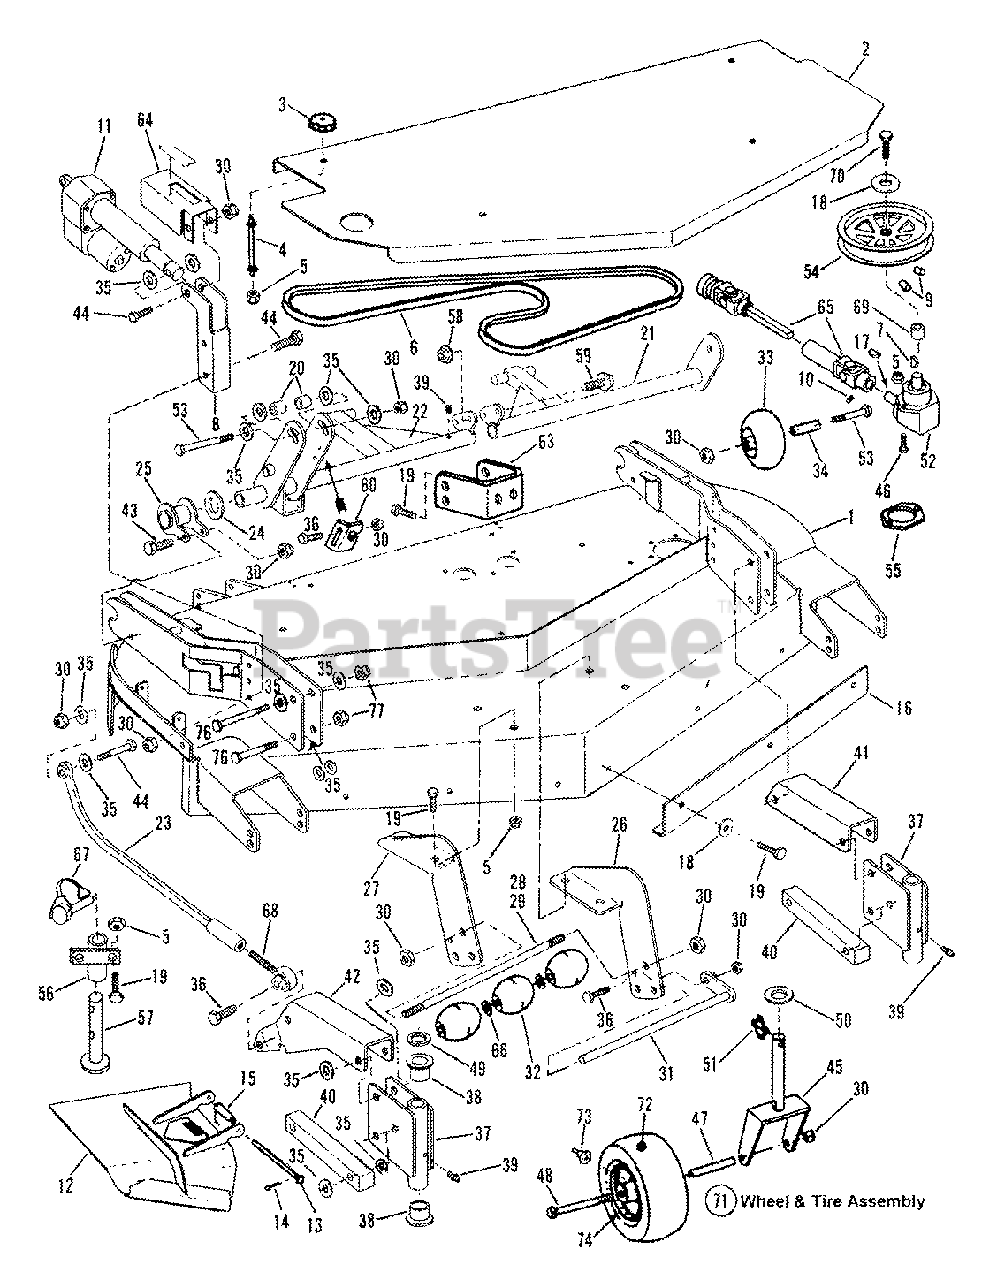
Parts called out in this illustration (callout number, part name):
1	WELDMENT, 61" Deck-Adjustable Height
2	COVER, 61" Deck
4	STANDOFF, 3-1/2"
5	NUT, 3/8-16 HEX NYLON LOCK
6	V-Belt, 61"(134.5") HB
7	KEY, 5/32 x 5/8 Woodruff
8	MOUNT, Motor (Front)
9	SCREW, 5/16-18 x 5/8" Set Yellow Zinc
10	SET SCREW, 3/8-16 x 3/8"
11	SCREWJACK, Warner Electric 1000 lbs.
12	DEFLECTOR, Chute 61" (Weldment)
13	PIN, Chute Hinge
14	PIN, 3/32 x 1" Cotter
15	SPRING, Chute
16	BAFFLE, Front
17	KEY. #9 Woodruff
18	WASHER, 13/32 x 1-1/2" Flat
19	BOLT, 3/8-16 X 1" GD5 CZ
20	SPACER, Motor, Rear
21	LINK, Weldment L.H.
22	LINK, Weldment R.H.
23	LINK, Height of Cut
24	SPACER, Tube
25	HOLDER, Pivot
26	MOUNT, Roller L.H.
27	MOUNT, Roller R.H.
28	TUBE, Roller
29	PIN, Roller
30	NUT, 1/2-13 Hex Nyloc
31	ASSEMBLY, Shaft
32	ROLLER, Low Density Polyethylene
33	WHEEL, Gage
34	SPACER, Gage Wheel
35	WASHER, 1/2" Flat
36	BOLT, 1/2-13 X 1-1/2 GD5 CZ
37	TUBE, Caster (Weldment)
38	BUSHING, Caster
39	FITTING, Lube 1/4-28 Straight
40	ARM, Lower Caster
41	ARM, Caster Support L.H.
42	ARM, Caster Support R.H.
43	BOLT, 1/2-13 x 3-3/4", Hex Head, Grade 5
44	BOLT, 1/2-13 X 3" GD5 CZ
45	WELDMENT, Caster
46	BOLT, 3/8-16 X 1-1/4" GD5 CZ
47	SLEEVE, Axle
48	BOLT, 1/2-13 X 5-1/2" GD5 YZ
49	SPACER, 1" x 1 3/8 x .30" (PM)
50	BUSHING, Machine
51	PIN, 7/16" HD Lynch
52	GEARBOX, Right Angle
53	BOLT, 1/2-13 X 5 GD5 YZ
54	PULLEY, Cast 5.45 O.D.
55	SHIM, Gearbox
56	TUBE, Jack stand (Weldment)
57	WELDMENT, Jack stand
58	NUT, 1/2-13 Hex Flange Lock, Grade 5
59	BOLT, 1/2-13 x 1-1/4" Hex Flange Lock, Grade 5
60	BRACKET, Strain Relief
63	BRACKET, Gage Wheel
64	INDICATOR, Height-of-Cut
65	ASSEMBLY, Telescoping Drive shaft
66	WASHER, 5/8" Flat
67	PIN, 5-16 Lynch
68	BALLJOINT, 1/2-20
69	SPACER
70	SCREW, 3/8-24 x 1", Gr. 5
71	ASSEMBLY, Wheel/Tire
72	TIRE, 9" x 3.50" -4 Ply
73	VALVE, Air (Snap-In)
74	RIM
76	SCREW, 1/2-20 x 4-1/2"
77	NUT, 1/2-20 Hex Nyloc
